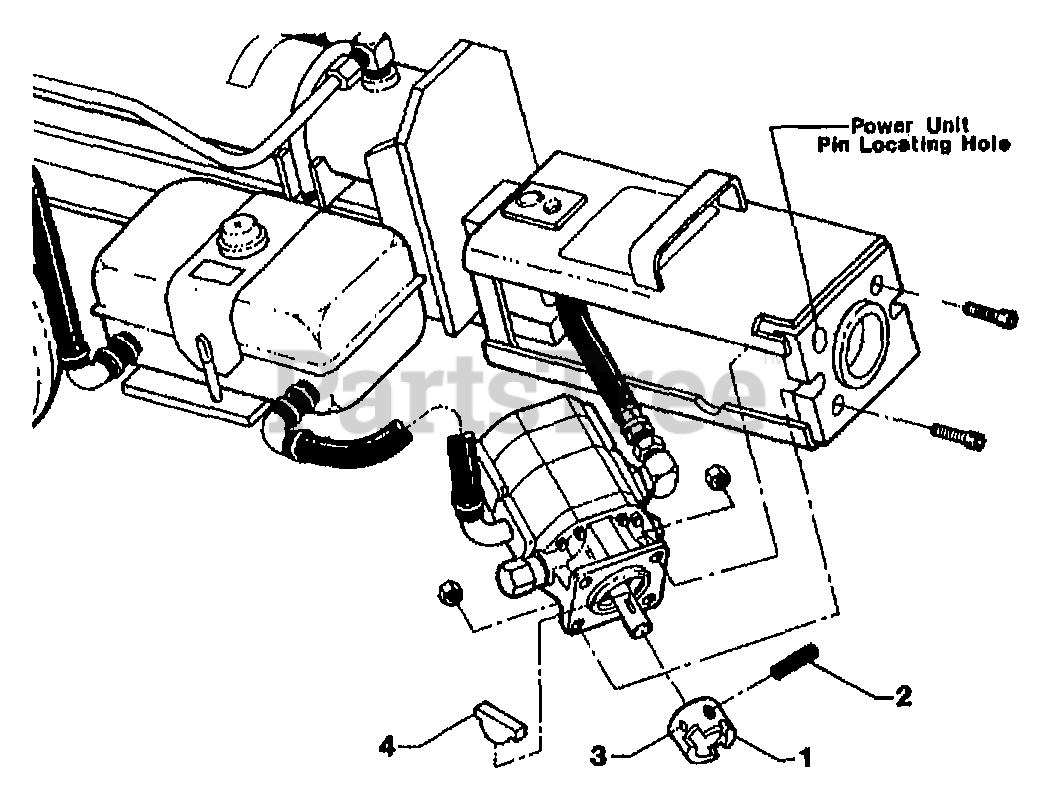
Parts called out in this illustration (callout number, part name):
1	CLUTCH-LOGSPLITTER MACH
2	SCR-SET HXSKT 1/4-20X.5NY
3	PIN-ROLL .125X1.375
4	KEY-HI PRO .125X.531
